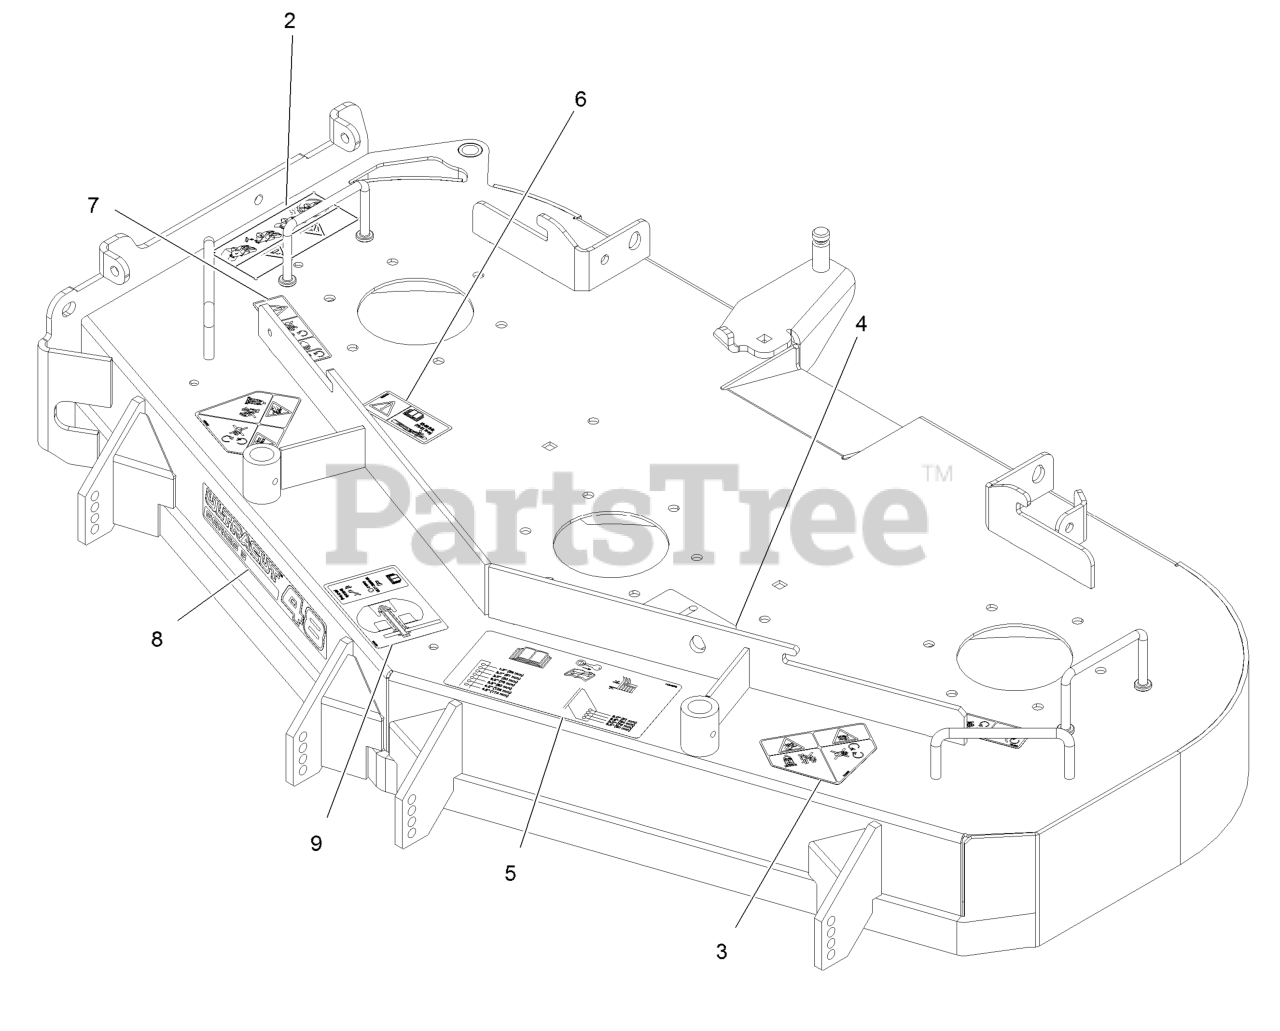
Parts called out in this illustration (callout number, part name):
2	Decal-Warning, Bagger
3	Decal-Danger
4	Decal-Belt Routing
5	Decal-Anti-Scalp
6	Decal-Bolt Torque
7	Decal-Cover, Missing
8	Decal-Ultracut 48 Series 3
9	Decal-Roller Mounting
